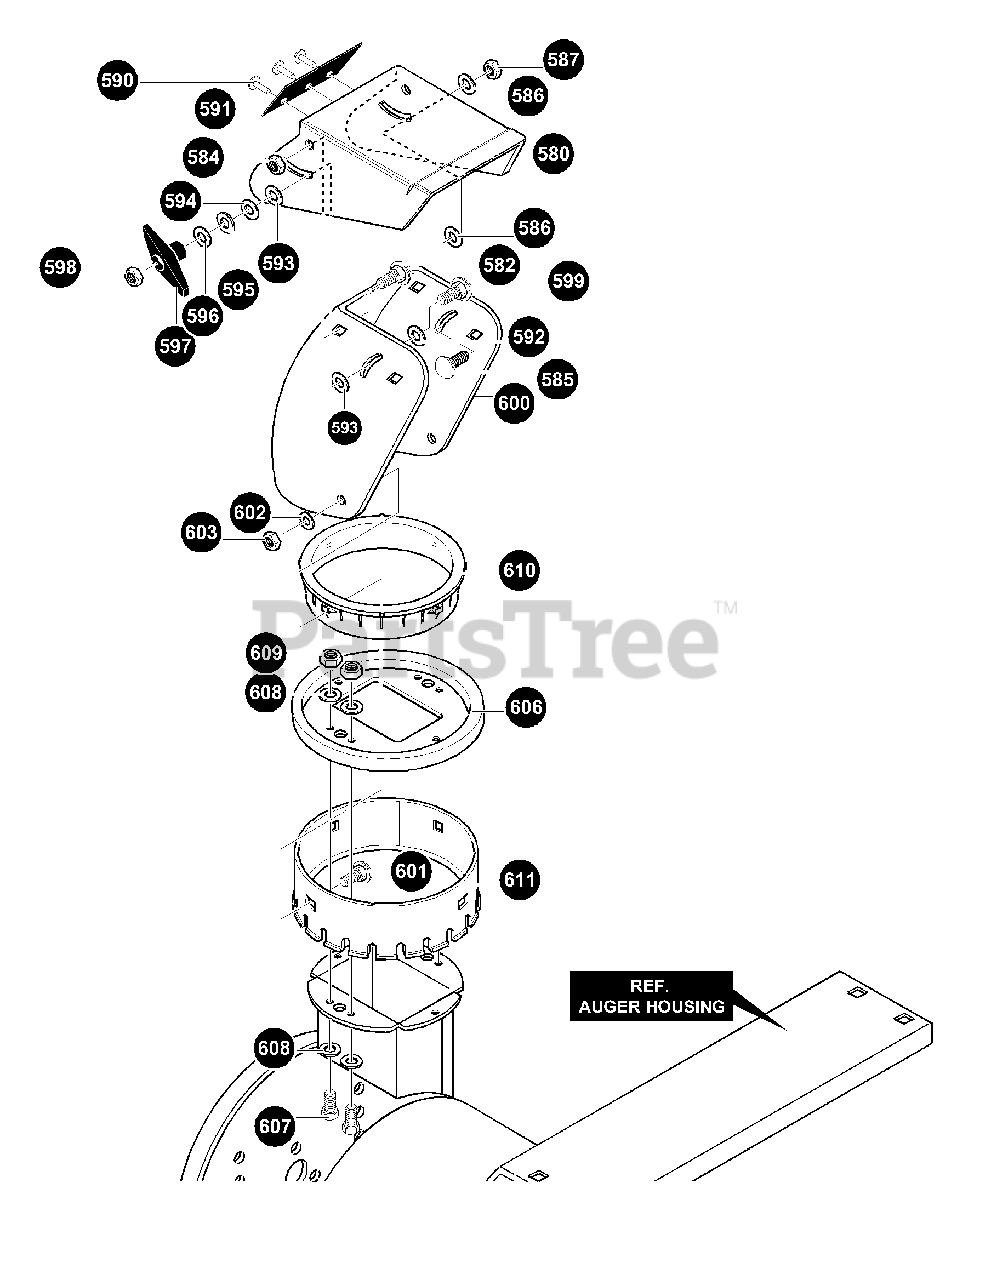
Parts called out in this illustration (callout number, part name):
580	CHUTE, UPPER
582	SCREW, 5/16-18X .75
584	NUT, 5/16-18
585	SCREW, 5/16-18X.75
586	WASHER, PLASTIC
587	NUT, 5/16-18
590	RIVET, POP
591	SKIRT, CHUTE EXT.
592	PLASTIC WASHER
593	PLASTIC WASHER
594	FLATWASHER
595	WASHER, HVSPTLK
596	FLATWASHER
597	KNOB, T 2 BLADE
598	NUT, 5/16-18 REGHEX
599	CARR. BOLT 5/16-18X1.00
600	CHUTE, LOWER
601	BOLT, 5/16-18X1.00
602	FLATWASHER .344X .69X.065
603	NUT, 5/16-18
606	COLLAR, CHUTE
607	SCREW, 1/4-20X .75
608	FLATWASHER .281X .63X.065
609	NUT, 1/4-20
610	Retainer, Ring Inner
611	Retainer, Ring Outer
